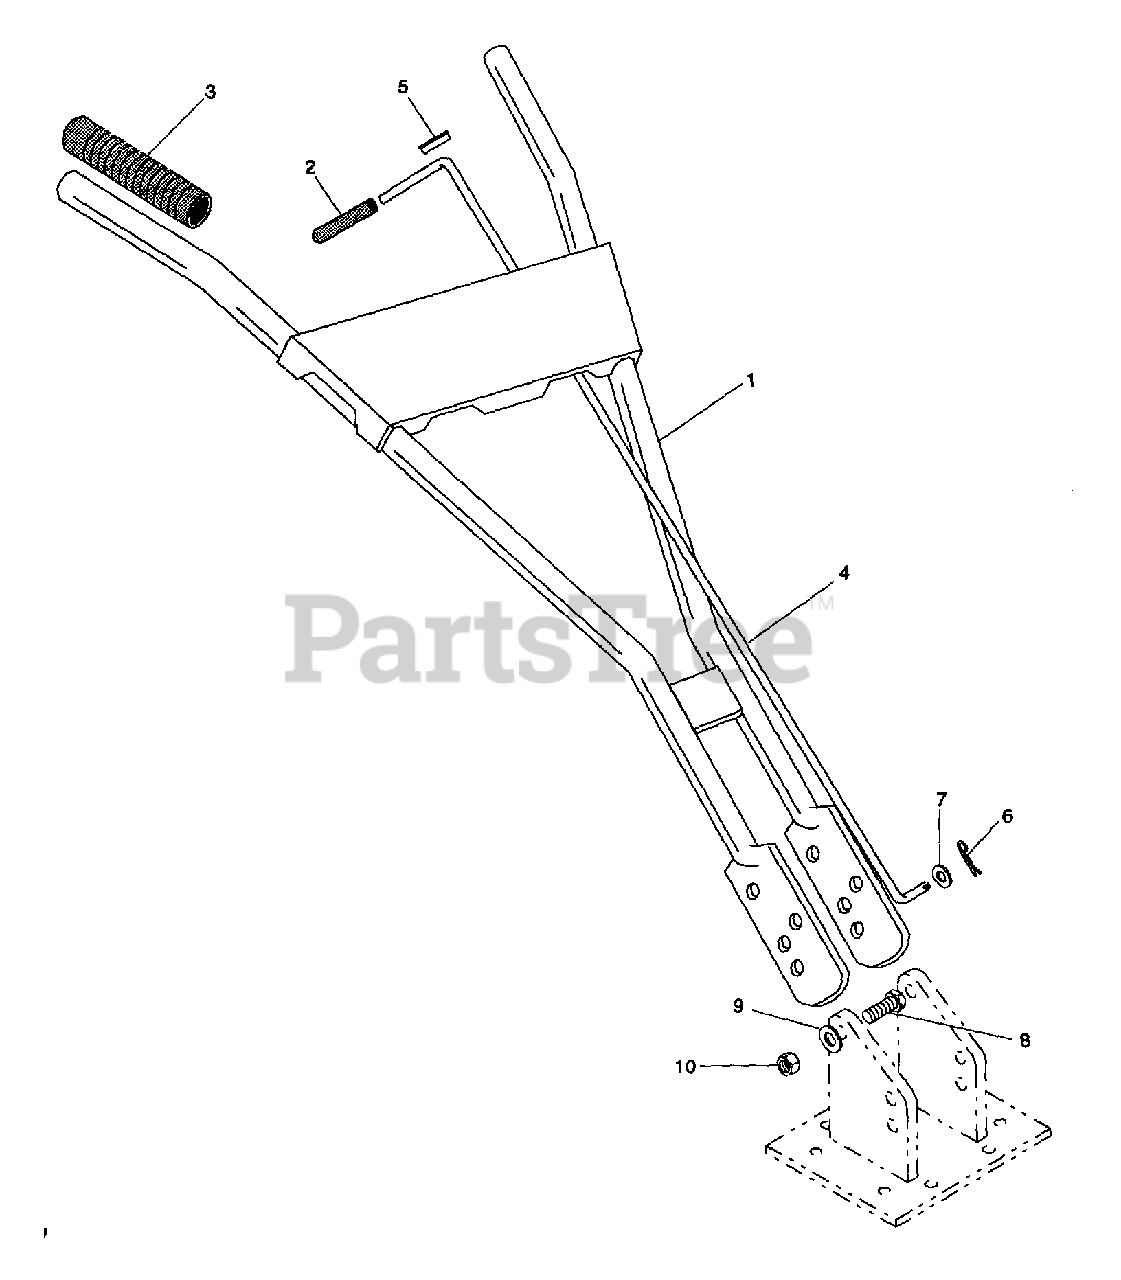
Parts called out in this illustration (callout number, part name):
1	HANDLEBAR RT 5018
2	GRIP - 5/16 ID X 2 7/8 - BLACK
3	HANDLEGRIP
4	SHIFT LEVER ROD
5	SNAP BUSHING
6	PIN-HAIR INT.06X.25X1.12
7	WSHR-FL-STL.344X.688X.065PL
8	BLT-HEX .38-16X1.00 PL
9	WSHR-FL-STL.406X.812X.065PL
10	NUT-LK-CTR .375-16 GR A PL
